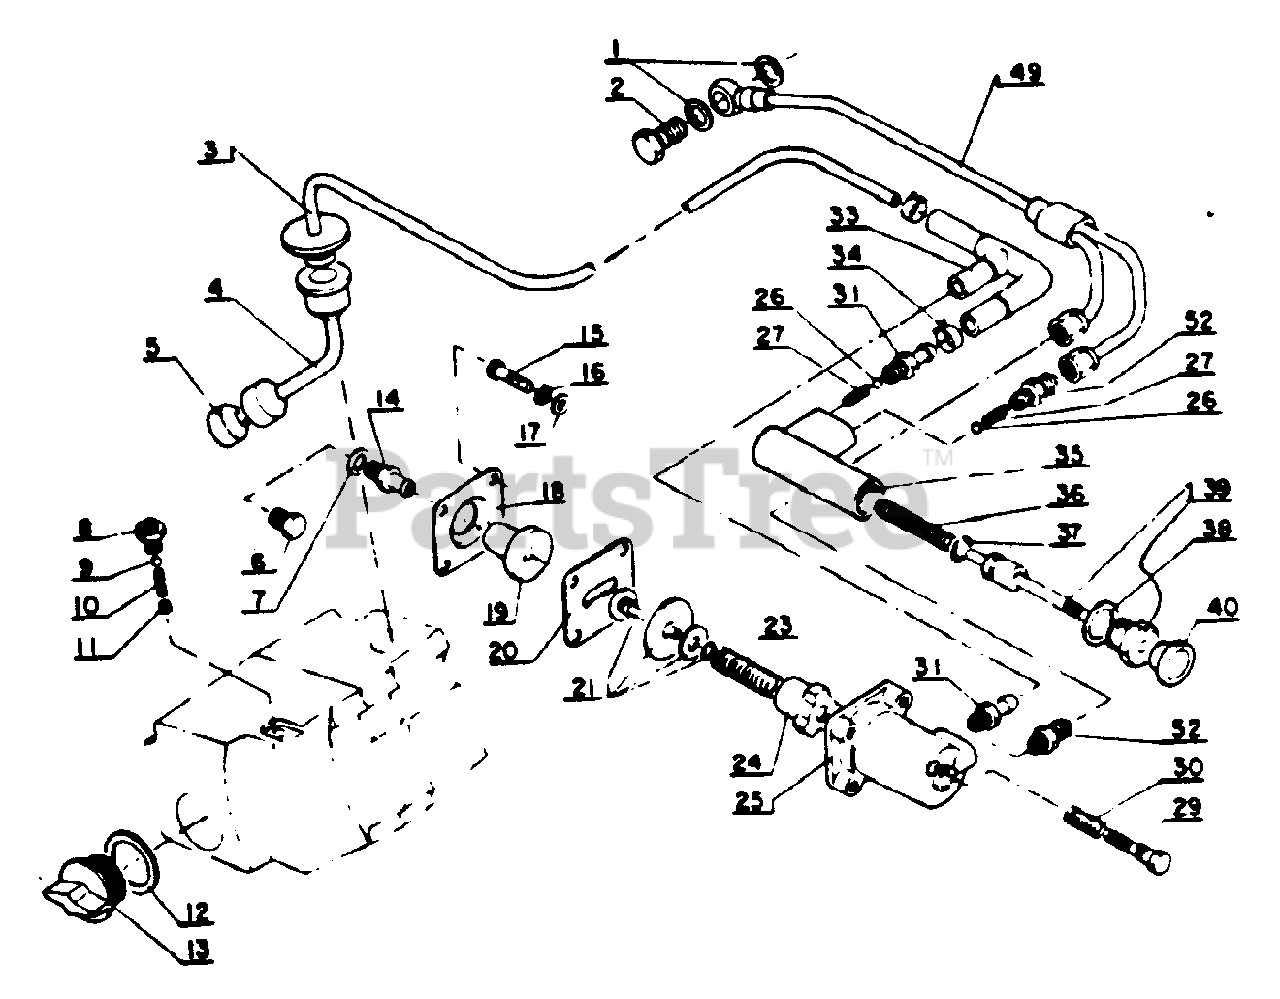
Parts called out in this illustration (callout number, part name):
2	BOLT, HOLDING
3	PIPE, OIL
4	PIPE, OIL
5	FILTER, OIL
6	PLUG (ADAPTER)
8	NUT, AIR BREED
9	VALVE, BALL
10	SPRING, AIR BLEED
11	PLUG, AIR BREED
13	OIL TANK CAP
15	SCREW
15	SCREW - 4×15
16	WASHER, SPRING 4 MM
17	WASHER 4 MM
18	RETAINER
19	CONNECTOR
21	PLUNGER ASSY
23	SPRING, ADJUST
24	SPRING CASE
25	CYLINDER, OIL
26	VALVE, BALL
29	SCREW, ADJUSTER
30	SPRING
31	CONNECTOR
32	PIPE, OIL
33	PIPE, OIL
34	CLIP
35	BODY, OIL PUMP
36	SPRING, OIL PUMP
37	O-RING
38	WASHER, LOCK
39	PISTON, OIL PUMP
39	PUMP PISTON
49	PIPE, OIL
52	CONNECTOR
